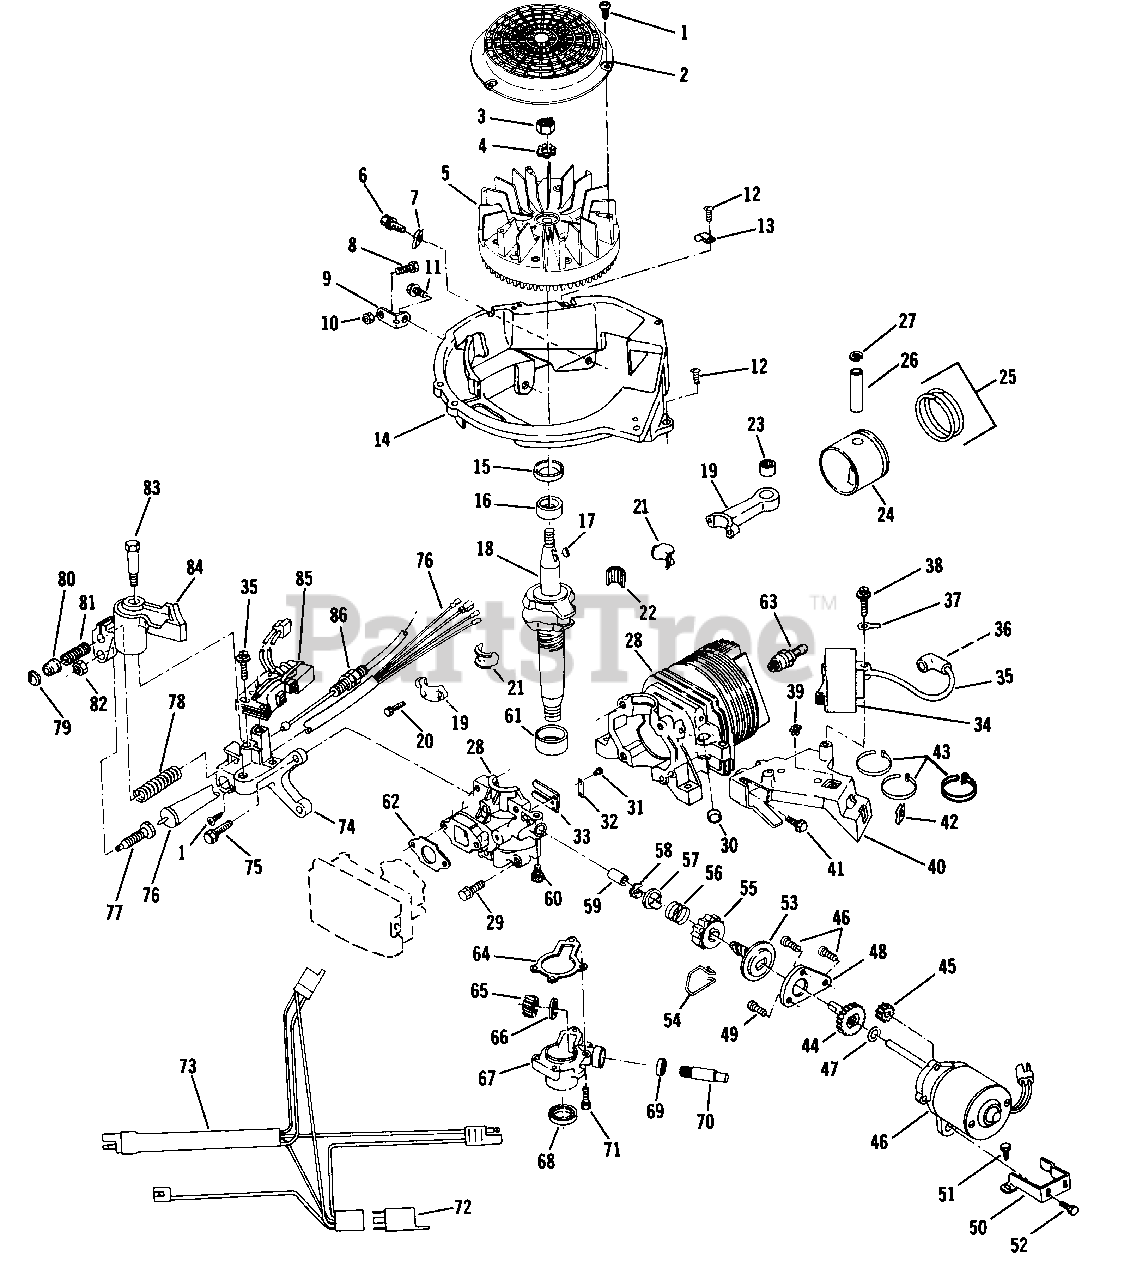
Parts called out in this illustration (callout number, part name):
1	Screw-Flywheel Screen and Switch
2	Flywheel Screen
3	Nut-Flywheel
4	Lockwasher
5	Flywheel
6	Screw
7	"J" Clip
8	Bolt-Brace-Alt. Brkt.
9	Brace-Alt. Bracket
10	Locknut-Brace-Alt. Brkt.
11	Screw
12	Screw-Shd. Base to C.D. Brkt. and Clamp to Shd. B.
13	Clamp
14	Base-Shroud
15	Oil Seal-Upper
16	Bearing-Upper
17	Key-Flywheel
18	Crankshaft
19	Connecting Rod Assembly.
20	Screw-Cap
21	Liner Split
22	Needle Bearing Set
23	Bearing Assembly
24	Piston and Ring Set
25	Ring Set
26	Wrist Pin
27	Retaining Ring
28	Cylinder and Crankcase Cover Assembly
29	Screw-Cover to Crankcase
30	Plug
31	Screw-Reed to C'case Cover
32	Plate-Reed Hold Down
33	Reed
34	C.D. Ignition Module and Lead Assembly
35	High Tension Lead and Cover Assembly
36	Spring Terminal
37	Terminal-Ground Lead
38	Screw-C.D. Mtg. and Alt. Mtg.
39	Grommet-C.D. Bracket
40	Bracket-Ignition Mtg.
41	Screw
42	Clip-"U"
43	Tie Strap
44	Gear-Driven
45	Pinion-Motor Shaft
46	Motor Housing and Pin Ass'y.
47	Washer
48	Plate-Gear Cover
49	Screw
50	Bracket-Starter Mtg.
51	Screw
52	Screw
53	Pinion, Spring and Clutch Ass'y.
54	Spring-Drag
55	Pinion
56	Spring-Pinion Return
57	Washer-Pinion Stop
58	Retaining Ring
59	Sleeve
60	Set Screw-Starter Assembly
61	Bearing-Lower
62	Gasket-Carb. to Crankcase Cov.
63	Spark Plug
64	Gasket-Gear Box
65	Gear
66	Washer-Thrust
67	Gear Box Assembly
68	Oil Seal Crankshaft
69	Seal-Driveshaft
70	Driveshaft
71	Screw-Gear Box
72	Relay
73	Wire Harness Assembly
74	Bracket-Alt. and Brake Mtg.
75	Screw-Alt. and Brake Mtg. Brkt.
76	Brake Switch Assembly
77	Plunger
78	Spring-Brake
79	Retainer
80	Actuator-Brake Lever
81	Spring-Cable Retainer
82	Nut
83	Bolt-Shoulder
84	Brake Assembly
85	Alternator Assembly
86	Control Cable Assembly
